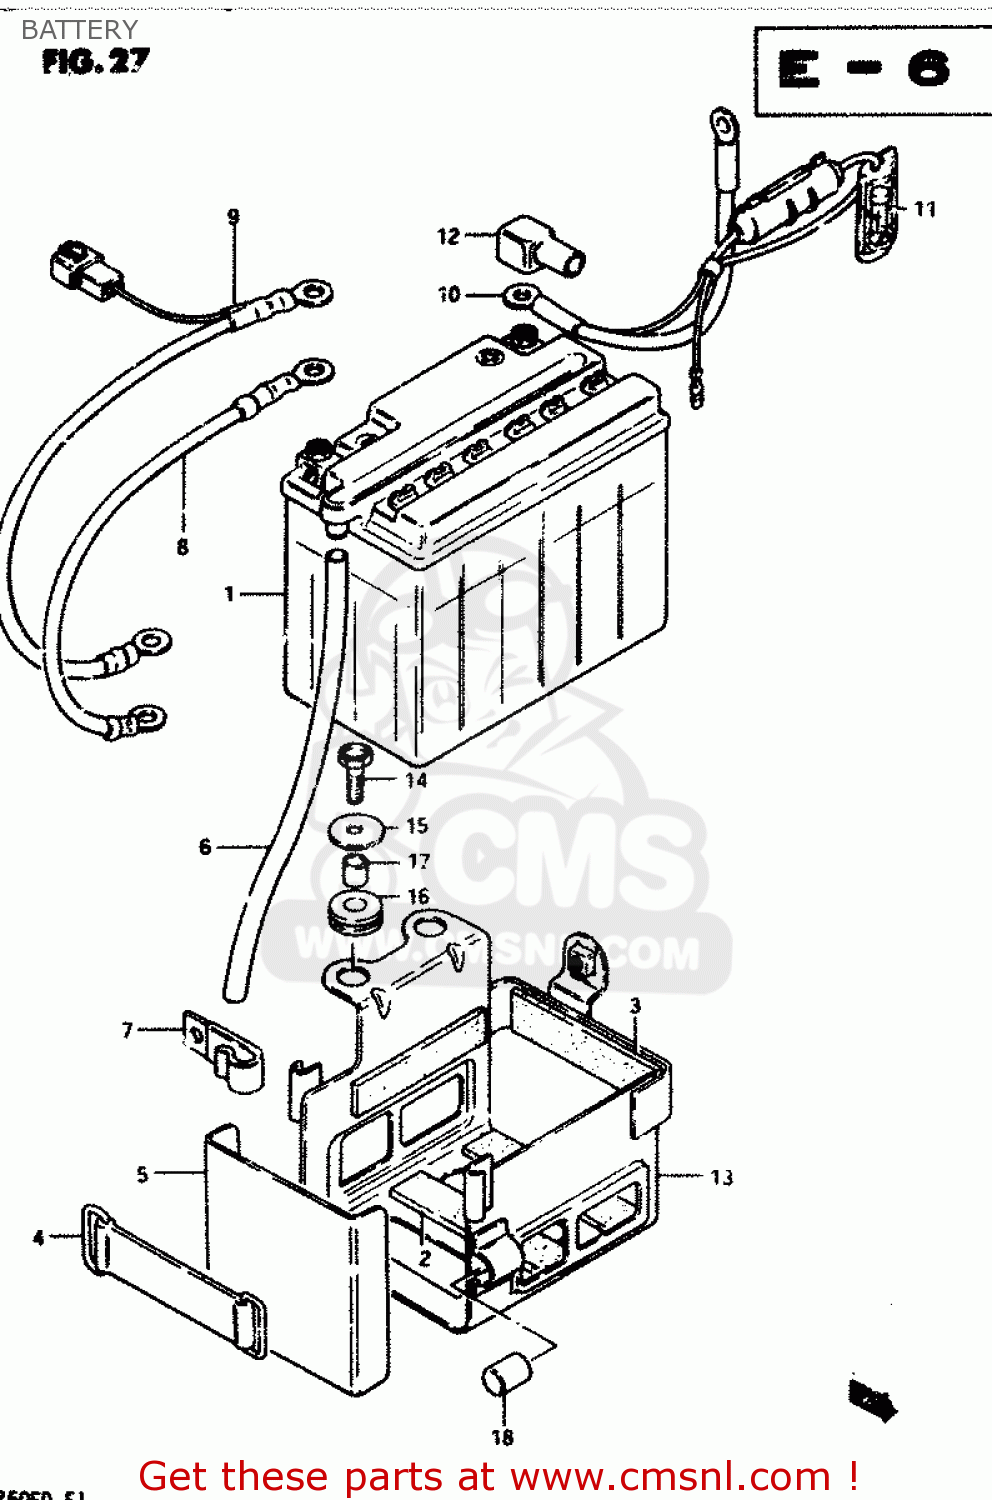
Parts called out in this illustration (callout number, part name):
1	BATTERY(YB12B-B2,12V11.6A)
2	PROTECTOR(20X90)X4
3	PROTECTOR,20X9
4	BAND
5	COVER,BATTERY
6	HOSE,BATTERY EXHAUST
7	CLAMP
8	LEAD WIRE,BATTERY(-)
9	CORD,BATTERY MINUS
10	FUSE CASE AND PLUS CABLE
11	FUSE(15A)
12	CAP,TERMINAL
13	HOLDER,BATTERY
14	BOLT
15	WASHER
16	CUSHION
17	SPACER (6.1X9X9)
18	CUSHION
